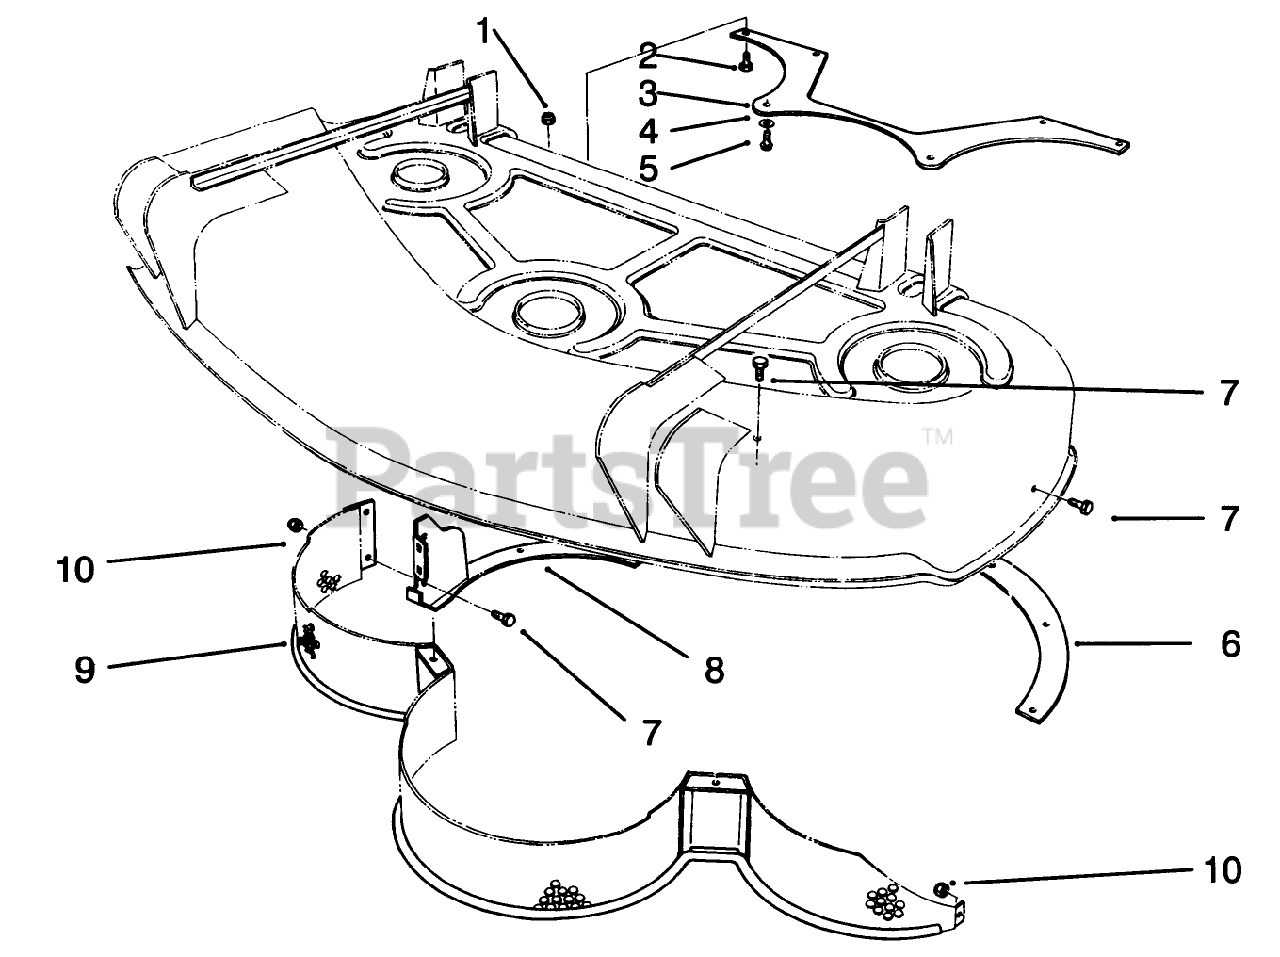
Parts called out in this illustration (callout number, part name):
1	NUT-LOCK, NI
2	SCREW-HH
3	Baffle Bagging
4	WASHER-FLAT
5	SCREW-HHFTF
6	RING - LH BAGGING R
7	SCREW-HH
8	Ring-Bagging RH
9	Screen
10	NUT-LOCK, NI
